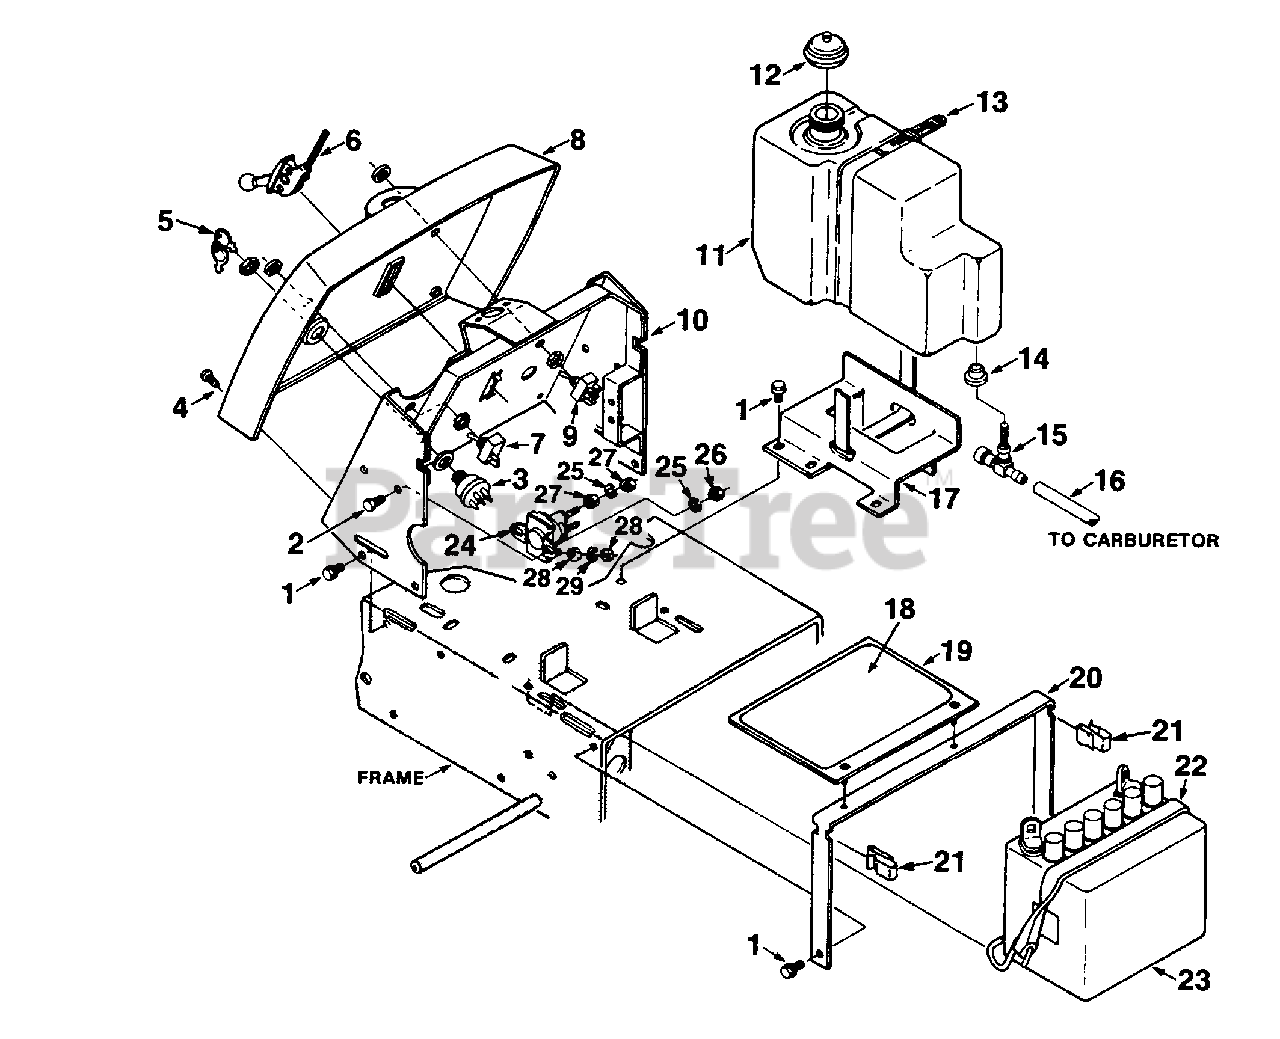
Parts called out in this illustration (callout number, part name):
1	BOLT- 1/4-14
2	SCREW- 1/4-20 x 1/2 hex
3	SWITCH- Key
8	PANEL- Dash
9	SWITCH- PTO
10	CONTROL TOWER ASSY.
11	TANK- Gas
12	CAP- Fuel
13	STRAP- Gas tank
15	VALVE- Shut off
16	TUBING- Rubber
18	DECAL- Battery
19	COVER- Battery
22	STRAP- Hold down
25	WASHER- Lock 1/4
26	NUT- Hex 1/4-20
29	WASHER- Lock
